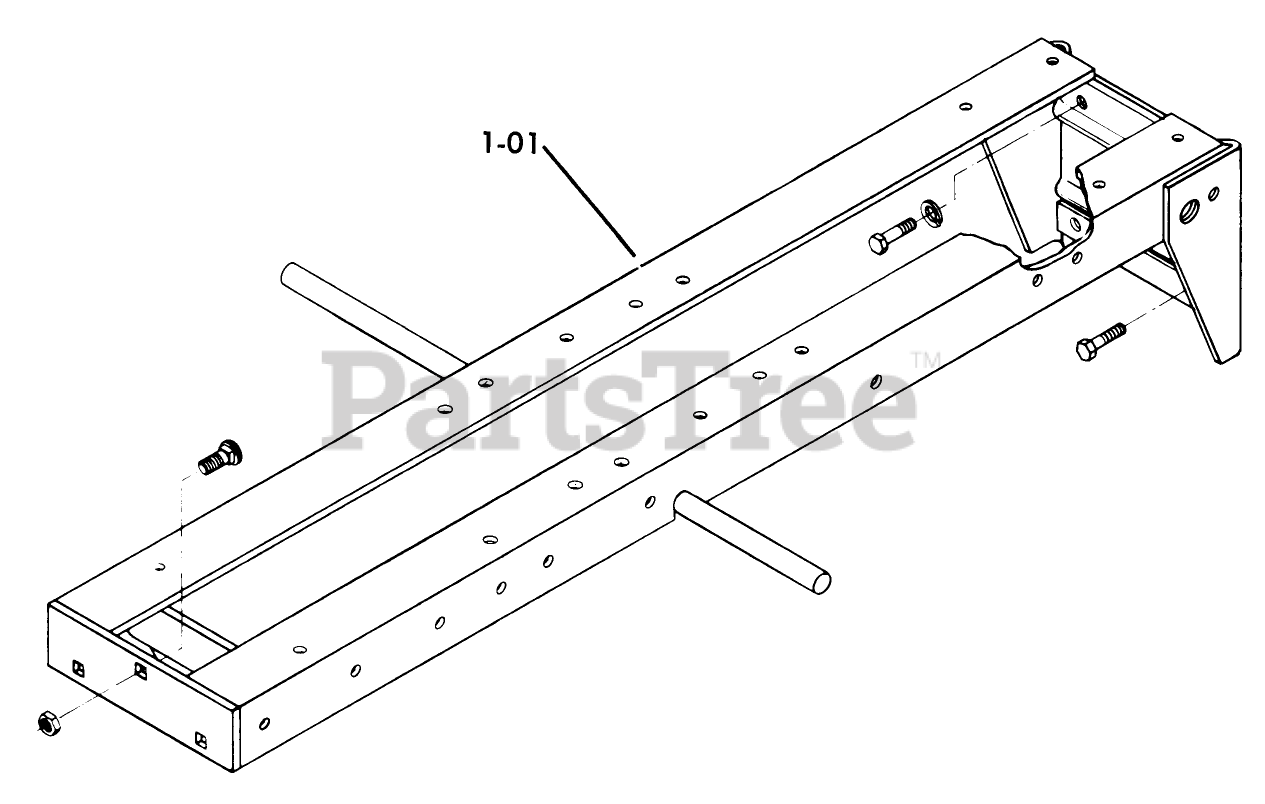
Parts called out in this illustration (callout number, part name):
1-01	Assy-Frame
1-01	Bolt
1-01	LOCKWASHER
1-01	Nut
